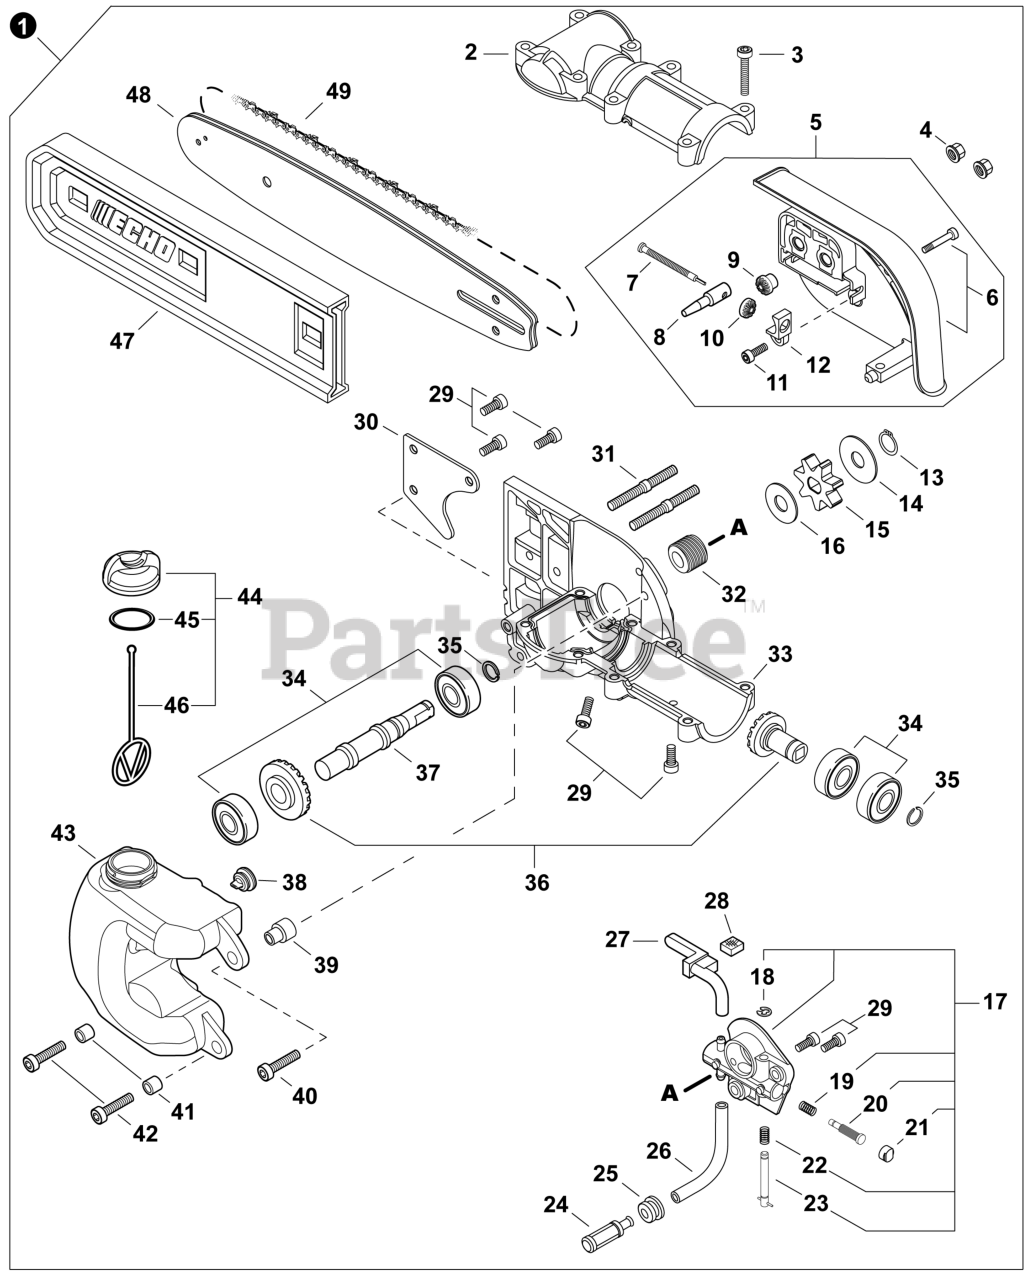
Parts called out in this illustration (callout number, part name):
1	CUTTING HEAD KIT
2	COVER, GEAR CASE
3	BOLT, TORX 5x25
4	NUT, FLANGE M6
5	SPROCKET GUARD ASSY
6	GUARD, SPROCKET
8	TENSIONER, CHAIN
9	GEAR - 14 TOOTH
10	GEAR - 14 TOOTH
11	SCREW 4
12	COLLAR 8
13	RING, SNAP
14	WASHER 10
15	SPROCKET, DRIVE
16	WASHER 10
17	AUTO-OILER ASSY
20	PLUNGER ASSY
21	CAP, PLUNGER
23	ADJUSTER, OILER
24	FILTER, OIL
26	PIPE 3x6x70
27	PIPE, OIL OUTLET
28	PAD, FOAM
29	BOLT, TORX 5x10
31	BOLT, STUD 6
32	GEAR, WORM
33	CASE, GEAR
34	BEARING, BALL
35	RING, SNAP 12
36	GEAR SET
37	SHAFT, GEAR
38	VENT ASSY
39	COLLAR 6
40	BOLT, TORX 5x25
41	SPACER 6.2x7.8x6
42	BOLT, TORX 5x20
43	TANK, OIL
44	CAP ASSY
45	O-RING 18
46	CONNECTOR, CAP L= 60 MM
47	SCABBARD 10"
48	GUIDE BAR, 10"
49	SAW CHAIN 10"
